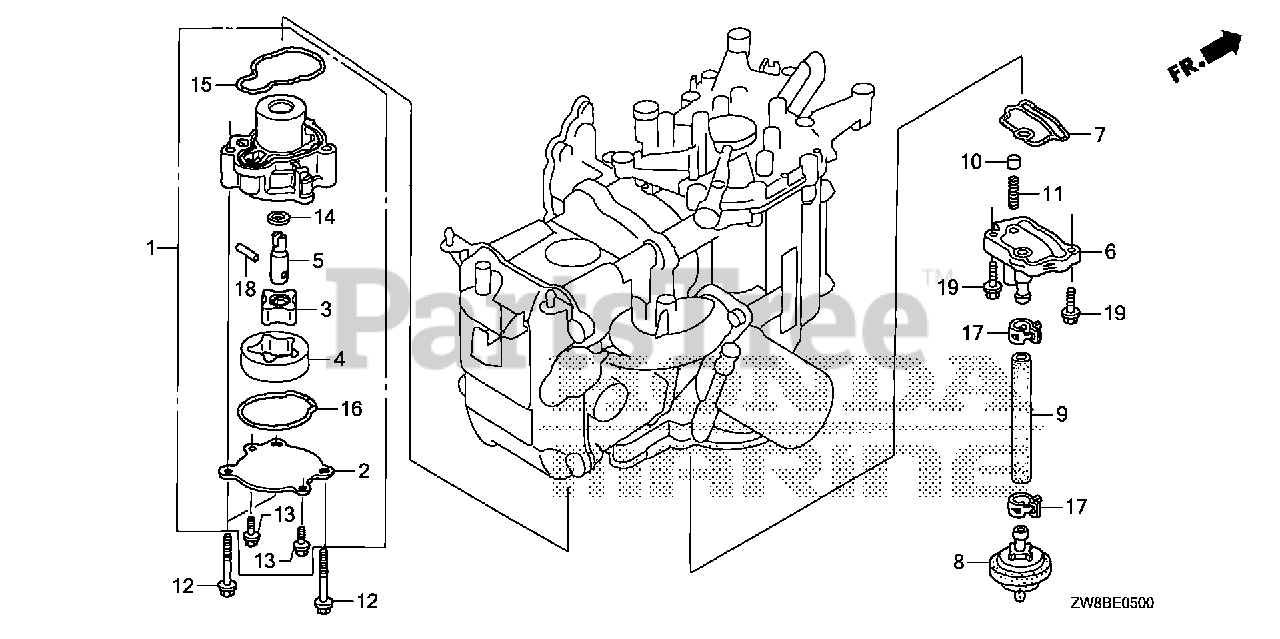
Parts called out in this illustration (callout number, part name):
1	PUMP ASSY., OIL
2	COVER, OIL PUMP
3	ROTOR, OIL PUMP (INNER)
4	ROTOR, OIL PUMP (OUTER)
5	SHAFT, OIL PUMP
6	FLANGE, OIL STRAINER
7	O-RING, OIL STRAINER FLANGE
8	STRAINER, OIL
10	VALVE, CHECK
11	SPRING, CHECK VALVE
12	BOLT, FLANGE (6X35)
13	BOLT, FLANGE (5X12) (CT200)
14	WASHER, THRUST (11MM)
15	O-RING, OIL PUMP
16	O-RING, PUMP COVER
17	CLAMP, TUBE (D17)
18	ROLLER (4X15.8)
19	BOLT, FLANGE (6X22)
